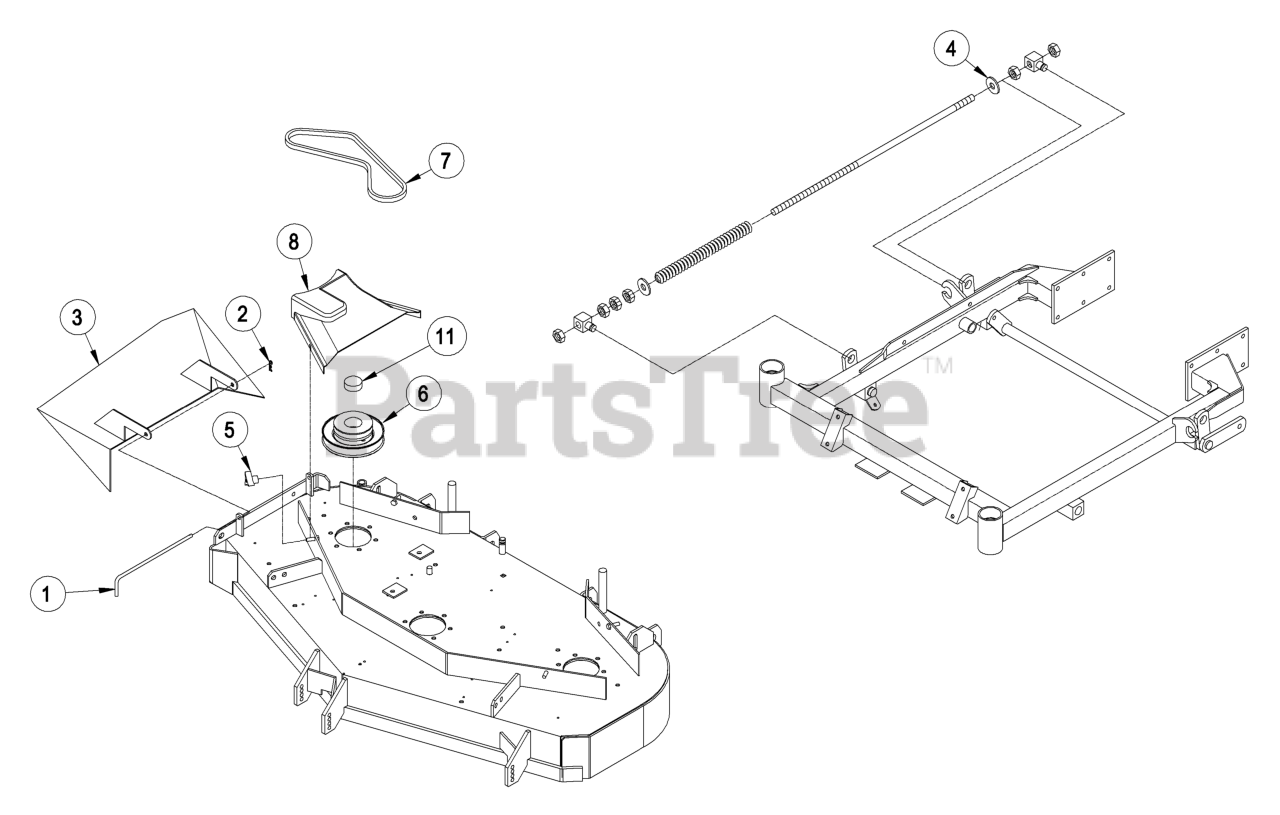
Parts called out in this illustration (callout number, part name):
1	PIN, CHUTE PIVOT PLTD
2	PIN-COTTER
3	Wld, Chute 48" Sd
4	2.25 O.D. Washer
5	KNOB-3 PRONG
6	SHEAVE, BLOWER DRIVE
7	BELT-BLOWER
8	COVER, BELT 44/48
9	Spacer, Counterweight
10	SCREW-HH
11	PLUG, BLACK NYLON 1.75
